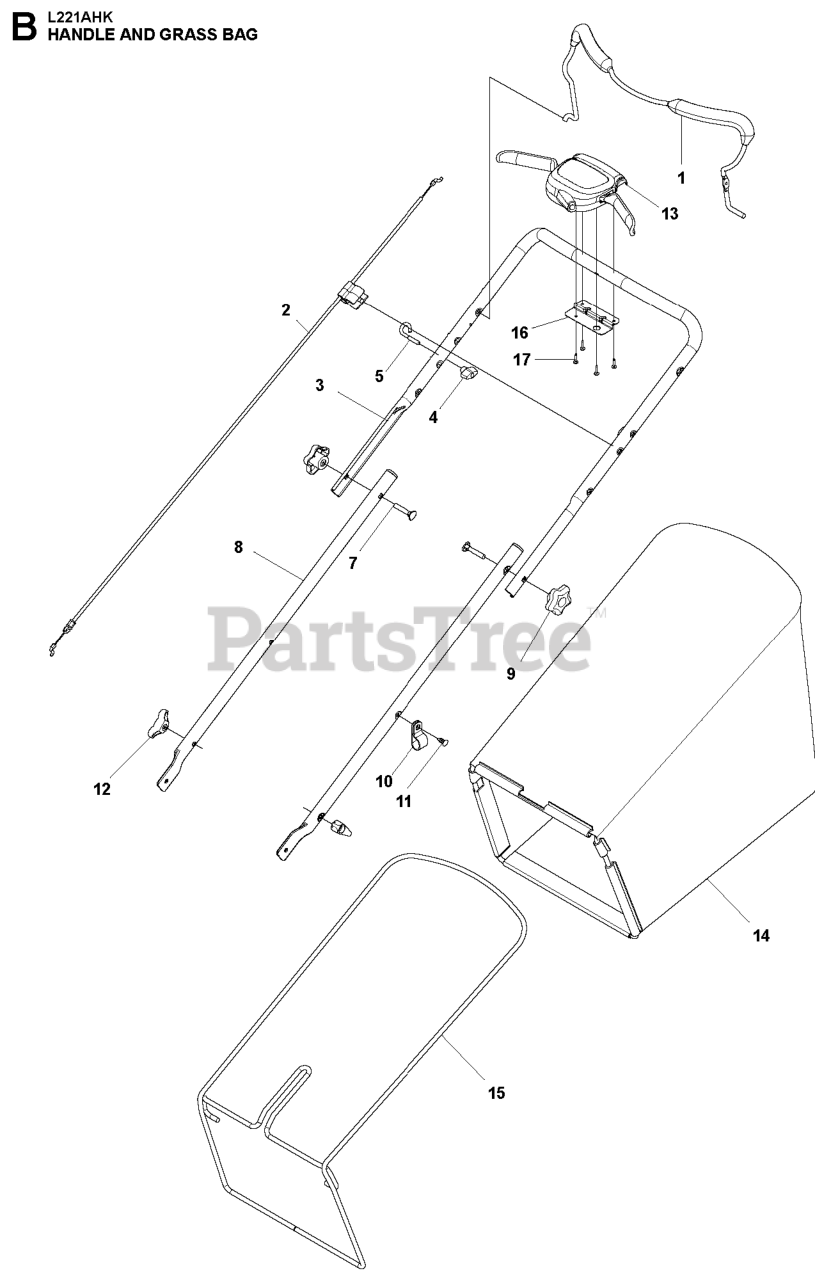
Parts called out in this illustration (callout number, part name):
1	BAIL.OM.ERGO.BENT.MZR.ORAN.668
2	CABLE.MZR.ZONE.CONTROL
3	HANDLE.UPPER.3.POS.BS.AW2.GREY
4	T-KNOB.NEW ROPE GUIDE
5	GUIDE.ROPE.BLK.ZINC.CHROM
7	BOLT.CONCAVE.HEAD.RETAINING
8	HANDLEBAR ASSY TWO PIECE LOWER
9	KNOB.HANDLE.PLASTIC.STAR.BLACK
10	CLIP.CABLE.BLK
11	FASTENER.PUSH.O.250X0.783
12	KNOB, DEFLECTOR
13	CONTROL.AW2.GEN.CURVED.AW/RGD.
14	GBAG.C361029EM.HUSQ.GRY.21EFF
15	FRAME.GBAG.AWD.21.BLACK
16	BRACKET DUAL TRIGGER CONTROL
17	SCREW, PHILLIPS HEAD 10 X 5/8
